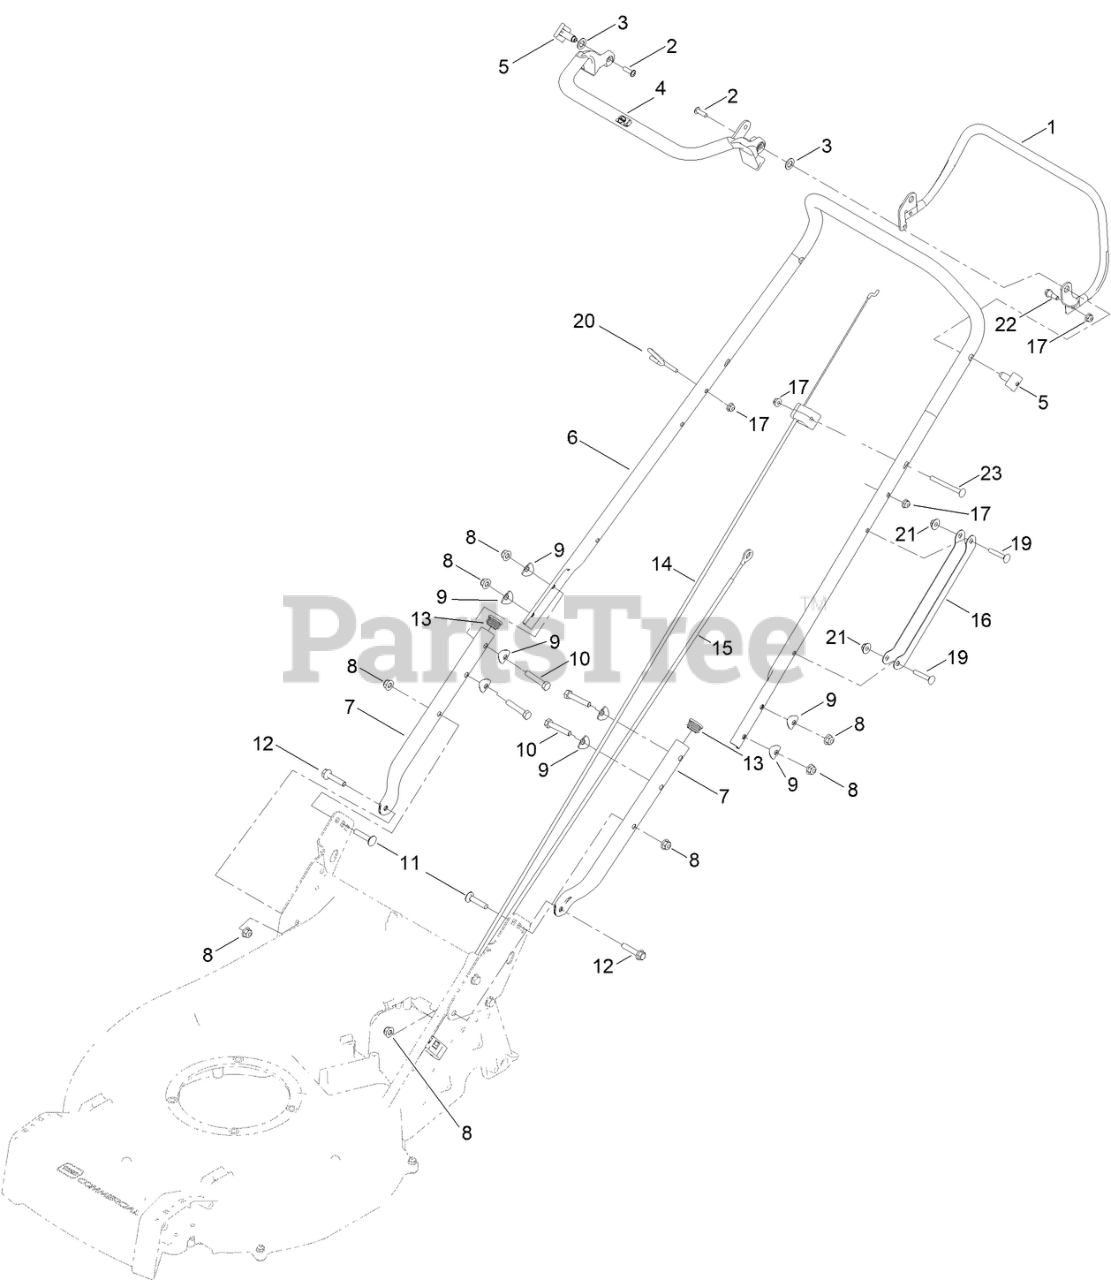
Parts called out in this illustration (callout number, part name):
1	LEVER-CLUTCH, GEARBOX
2	SCREW
3	WASHER-NYLON
4	OPC LEVER - ENGINE
5	PIN-PIVOT
6	HANDLE-UPPER
7	LOWER HANDLE
8	NUT-HF, NI
9	WASHER-CUP
10	SCREW-HH
11	BOLT-CARR
12	SCREW-HHF
13	PLUG-ROUND TUBE, 1 IN.
14	CABLE-TRACTION
15	CABLE-TRACTION
16	GUARD-CABLE, HANDLE
17	NUT-HF
19	SCREW-CARR
20	GUIDE-ROPE
21	NUT-HF
22	BOLT-SHOULDER
23	SCREW-CARR
